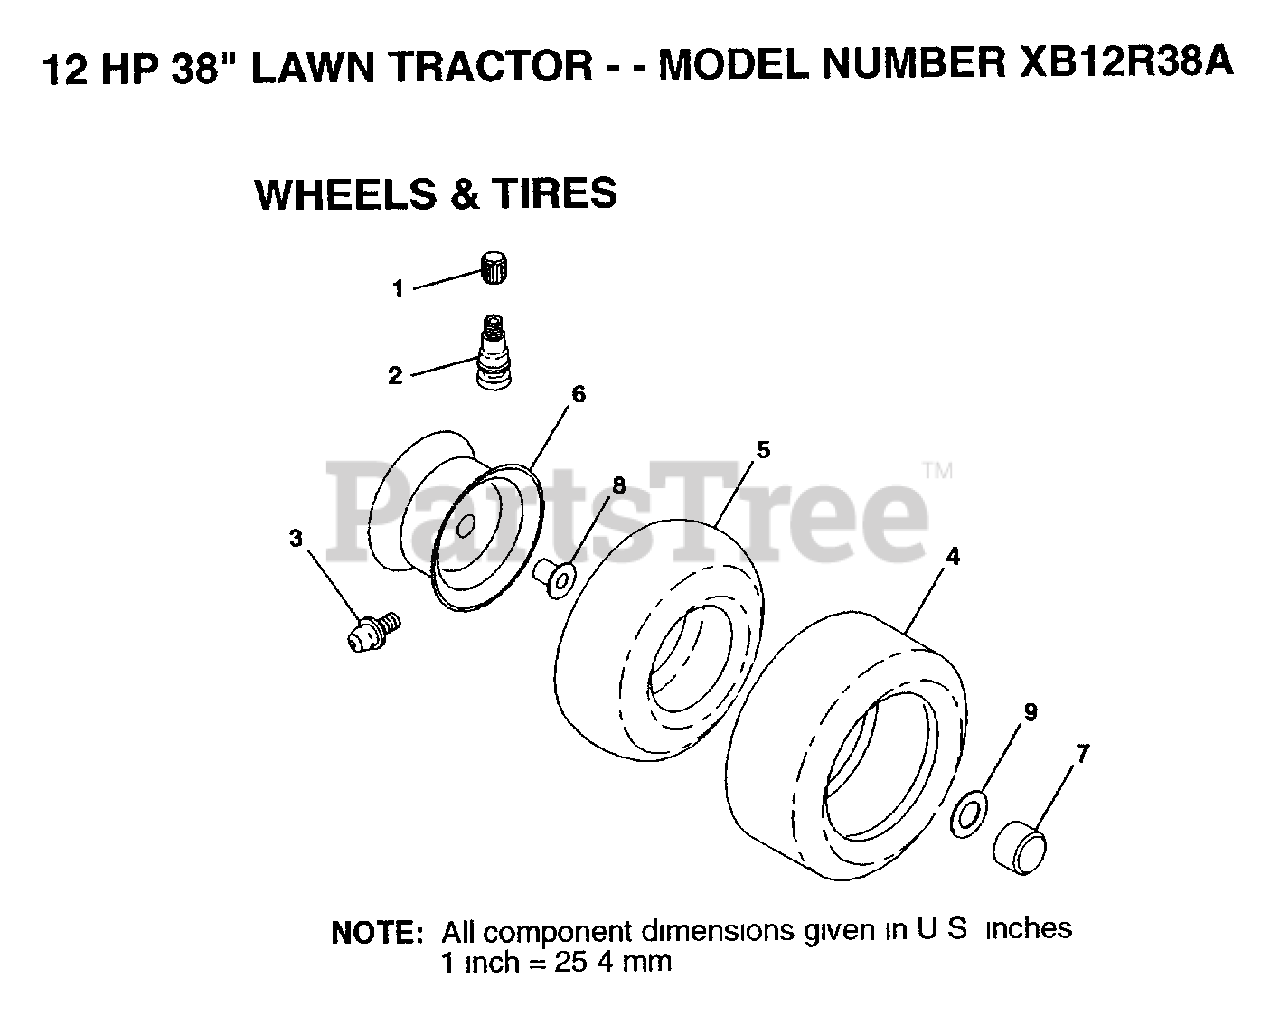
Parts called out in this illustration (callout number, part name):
1	VALVE CAP
2	VALVE STEM LT
3	FITTING LT
5	TUBE.5.3/4.5/6
7	HUB CAP
8	"FLANGE, BEARING"
9	WASHER
